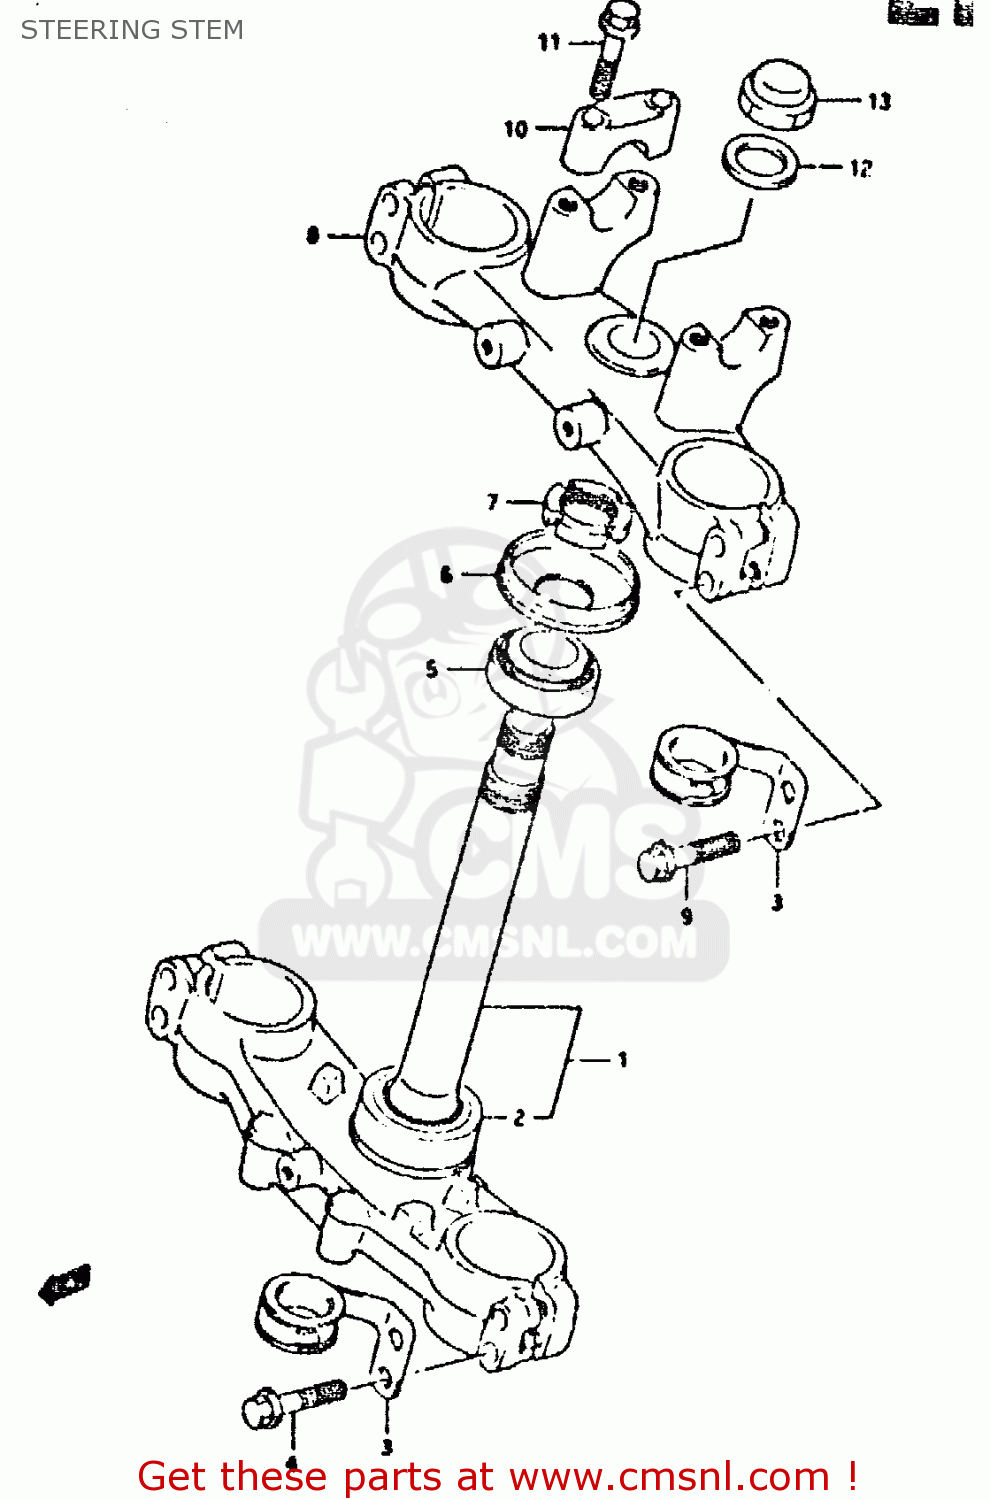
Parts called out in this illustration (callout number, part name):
1	STEM,STEERING
2	BEARING(30X55X17)
3	GUIDE,CABLE LWR,L
4	BOLT
5	TAPER,ROLLER BEARING
6	SEAL,STEERING UPR DUST
7	NUT,STEERING STEM
8	HEAD,STEERING STEM
9	BOLT
10	HOLDER,HANDLE UPR
11	BOLT
12	WASHER
13	NUT
